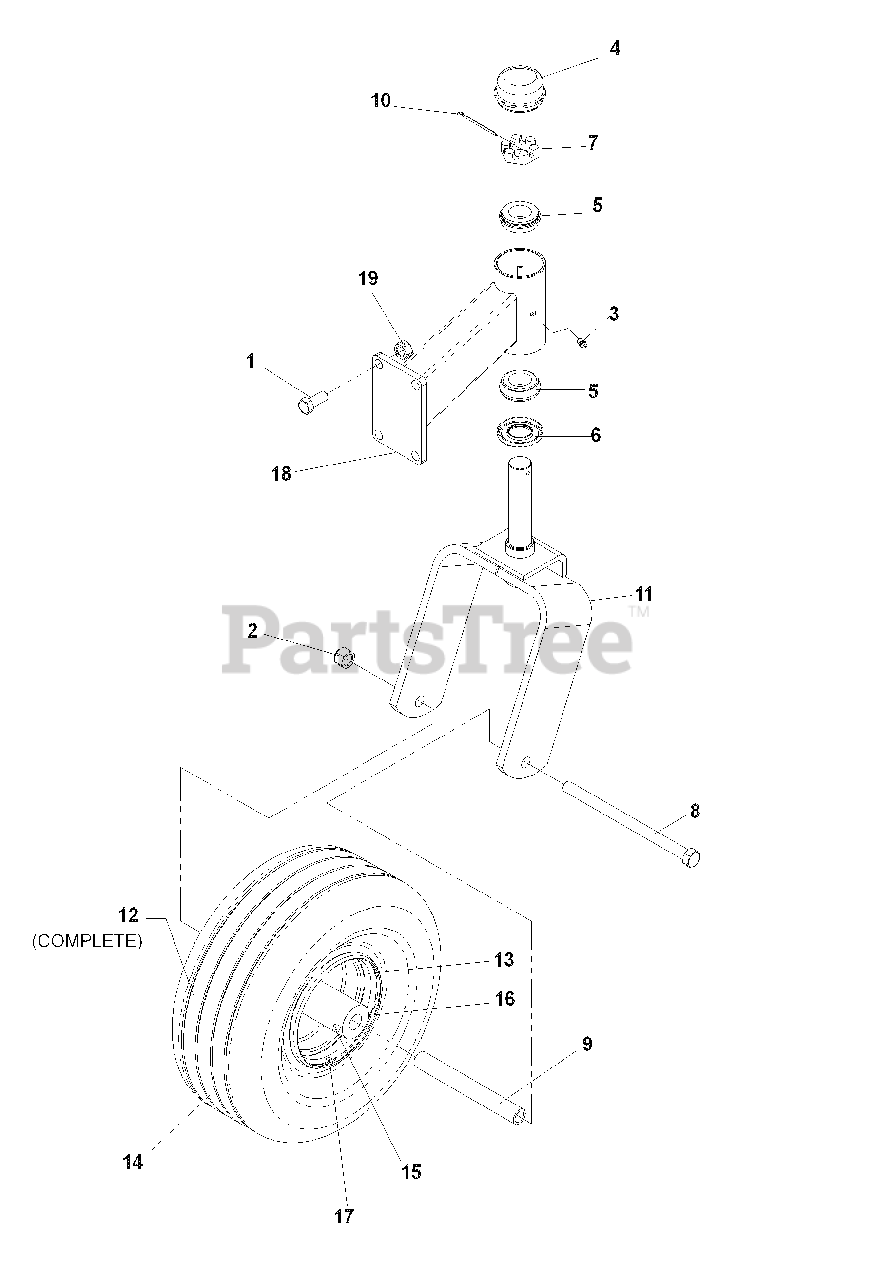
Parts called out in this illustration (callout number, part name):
1	HCS, 7/16-14 X 1
2	NUT, 1/2-13, NYLOC
4	CAP GREASE
5	BEARING, TAPERED
7	NUT, 1-14, JAM, SPEC
8	HCS, 1/2-13 X 7 1/2
10	PIN COTTER, 1/8 X 2
11	CASTER YOKE
12	TIRE, COMPLETE
13	RIM
14	TIRE
17	VALVE STEM
18	CASTER ARM
19	NUT, 7/16-14, CNTRLCK, GR A
